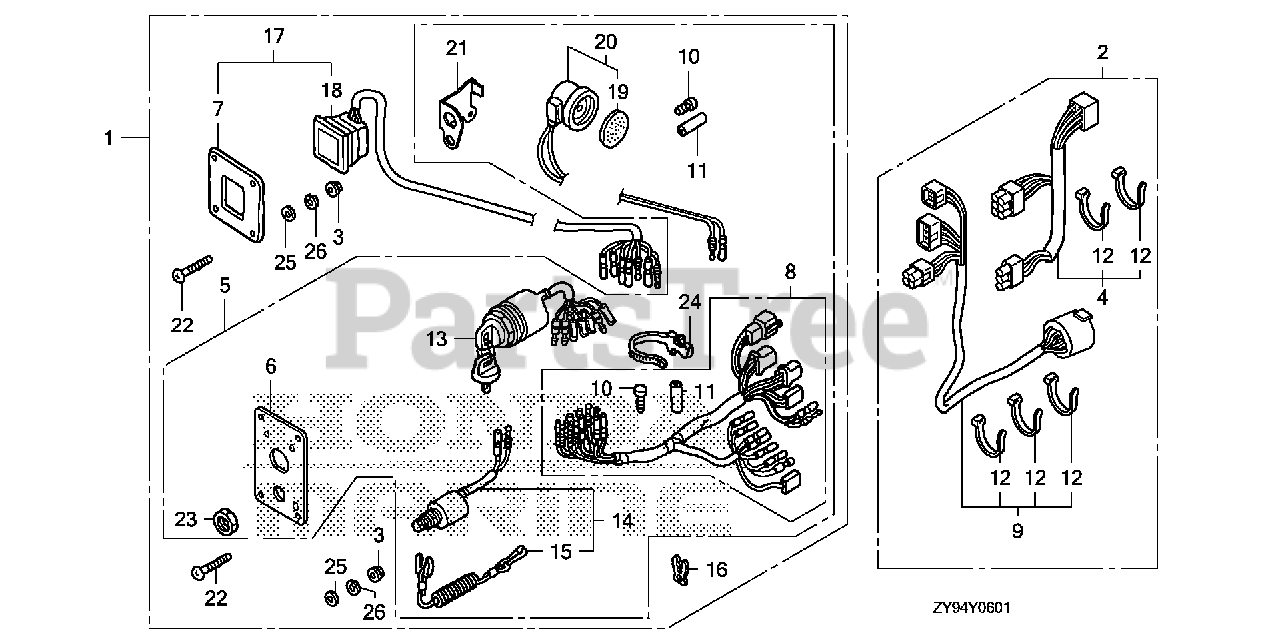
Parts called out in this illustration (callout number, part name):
1	PANEL KIT, SWITCH (4-LED) (B)
2	CABLE SET, PANEL INDICATOR (20FT)
2	CABLE SET, PANEL INDICATOR (25FT)
2	CABLE SET, PANEL INDICATOR (30FT)
3	NUT, FLANGE (5MM) DUAL QTY = (8) (SINGLE)
4	WIRE ASSY., INDICATOR (20FT)
4	WIRE ASSY., INDICATOR (25FT)
4	WIRE ASSY., INDICATOR (30FT)
5	PANEL ASSY., SWITCH
6	PANEL, CONTROL
7	PANEL, CONTROL
8	HARNESS ASSY., SWITCH PANEL
9	CABLE ASSY., SWITCH PANEL (20FT) (NHK MEC)
9	CABLE ASSY., SWITCH PANEL (25FT) (NHK MEC)
9	CABLE ASSY., SWITCH PANEL (30FT) (NHK MEC)
9	CABLE ASSY., SWITCH PANEL (30FT) (FOR 4-LED)
10	PLUG, CONNECTOR (INNER) (TROLLING CONTROL)
11	PLUG, CONNECTOR (OUTER) (ENGINE NO.)
12	TIE, CABLE (NATURAL 2.4X92) Use up to Frame SN 1300359.
13	SWITCH ASSY., COMBINATION (SINGLE) (DUAL)
14	SWITCH ASSY., EMERGENCY STOP
15	WIRE, EMERGENCY (SINGLE) (DUAL)
16	CLIP, EMERGENCY LOCK
17	PANEL ASSY., INDICATOR (4-LED)
18	LAMP ASSY., INDICATION (4-LED)
19	PLATE, TURN SIGNAL BUZZER DUAL QTY = (2) (SINGLE)
20	BUZZER, WARNING DUAL QTY = (2) (SINGLE)
21	BRACKET, BUZZER
22	SCREW, PAN (5X40) DUAL QTY = (8) (SINGLE)
23	NUT, HEX. (16MM) DUAL QTY = (2) (SINGLE)
24	BAND, WIRE HARNESS (150MM) (NATURAL) DUAL QTY = (2) (SINGLE)
25	WASHER, PLAIN (5MM) DUAL QTY = (8) (SINGLE)
26	WASHER, SPRING (5MM) DUAL QTY = (8) (SINGLE)
